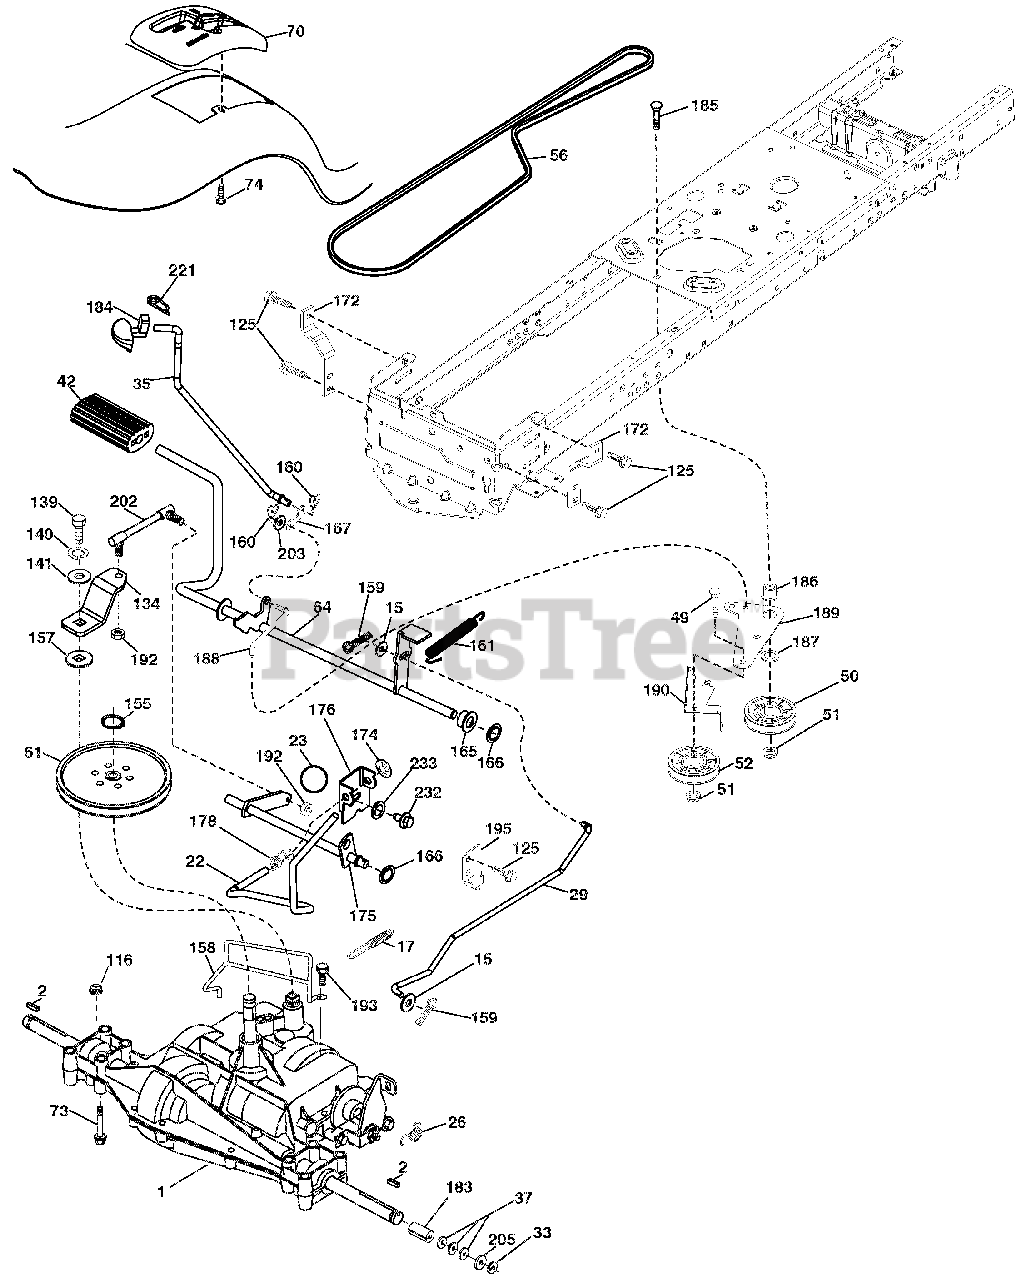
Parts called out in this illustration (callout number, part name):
2	KEY.SQUARE.2.0 X .1845/.1865
15	WASHER.13/32 X 13/16 X 16 GA.
17	SPRING.BRAKE.PEERLESS/D6800.TX
22	ROD.SHIFT.FENDER.TLT.2006
23	GRIP.LEVER..5625 ID.BLACK 428
26	SPRING.BRAKE.RTN.GR DR.TEX.006
29	ROD.BRAKE.PEERLESS/D6800
33	E-RING.#5133-75
35	ROD.BRAKE.PARKING.LT.TEX
37	WASHER.25/32 X 1 1/4 X 16 GA.
42	COVER.PEDAL.BLK.ROUND
49	BOLT.RDHD.3/8-16UNCX1-3/4.GR5
50	IDLER.FLAT.910"OFFSET
51	Nut, Hex, Flangelock 3/8-16
52	IDLER.V-GROOVE.910"OFFSET
56	V-BELT.DRV.97.40"PMST/DANA
61	PULLEY.TRANSAXLE.18/20"TIRES
64	SHAFT ASM.PEDAL.BRAKE CONTROL
70	CONSOLE.SHIFT.STL.6SP.BLACK.TX
73	BOLT.HEX.FLGHD.5/16-18.GR.5
74	SCREW.HEX.WSH.HI-LO.1/4X1/2UNC
116	Nut, Lock Hex Flange 5/16-18 u
125	SCREW.5/16-18X3/4.SMGML.TAP/BL
134	ARM.SHIFT.T/A.PMST.18"LT.TEX
139	BOLT.1/4-28 UNF.GR8.W/PATCH
140	Washer, Lock 1/4
141	WASHER.9/32 X 3/4 X 10 GA.
155	Ring, Retainer
157	WASHER.PLATE.SHF..388 SQ.HOLE
158	KEEPER.T/A.PMS/D4360/D680.1820
159	PIN.COTTER.1/8 X 3/4.CAD.
160	RETAINER.CLIP(M).DIA.290
161	SPRING.RETURN.CLUTCH.6.75
165	BUSHING.SHAFT.BRAKE.HAND CONTR
166	NUT.PUSH..625.2006
167	LATCH.BRAKE.PARKING
172	STRAP.TRQ.LH.GEAR DRIVE.LT.TEX
174	NUT.PUSH..500
175	SHAFT ASM.SHIFT.GR DRV.18"LTEX
176	ARM.CLEVIS.ROD.SHIFT
178	SPRING.SHIFT.GT.2006
183	SPACER.AXLE.HYDRO/PEERLES
184	HANDLE.PARKING BRAKE.LTTEX.505
185	BOLT.RDHD.3/8-16UNC X2-3/4 GR5
186	SPACER.RETAINER
187	WASHER.13/32 X 2 X 10 GA.
188	LINK.CLUTCH.GROUND DRIVE
189	BELLCRANK.GROUNDRIVE.NSTG/NSTL
190	KEEPER.BELLCRANK.DRIVE.GROUND
192	NUT.LOCK.CENTER.1/4-28 FNTHD.
193	SCREW.5/16-18X3/4.SMGML.TAP/R
195	BRACKET.ROD.BRK.PEERLESS/D6800
202	LINK.SHIFT PMST.18HP
203	Washer 11/32 x 11/16 x 16 Ga.
205	WASHER.25/32 X 1-5/8 X 16GA.
221	RETAINER.SPRING.CLIP.HANDLE
232	BOLT.FIN HEX.7/16-14X1 GR5
233	WASHER.SERRATED
